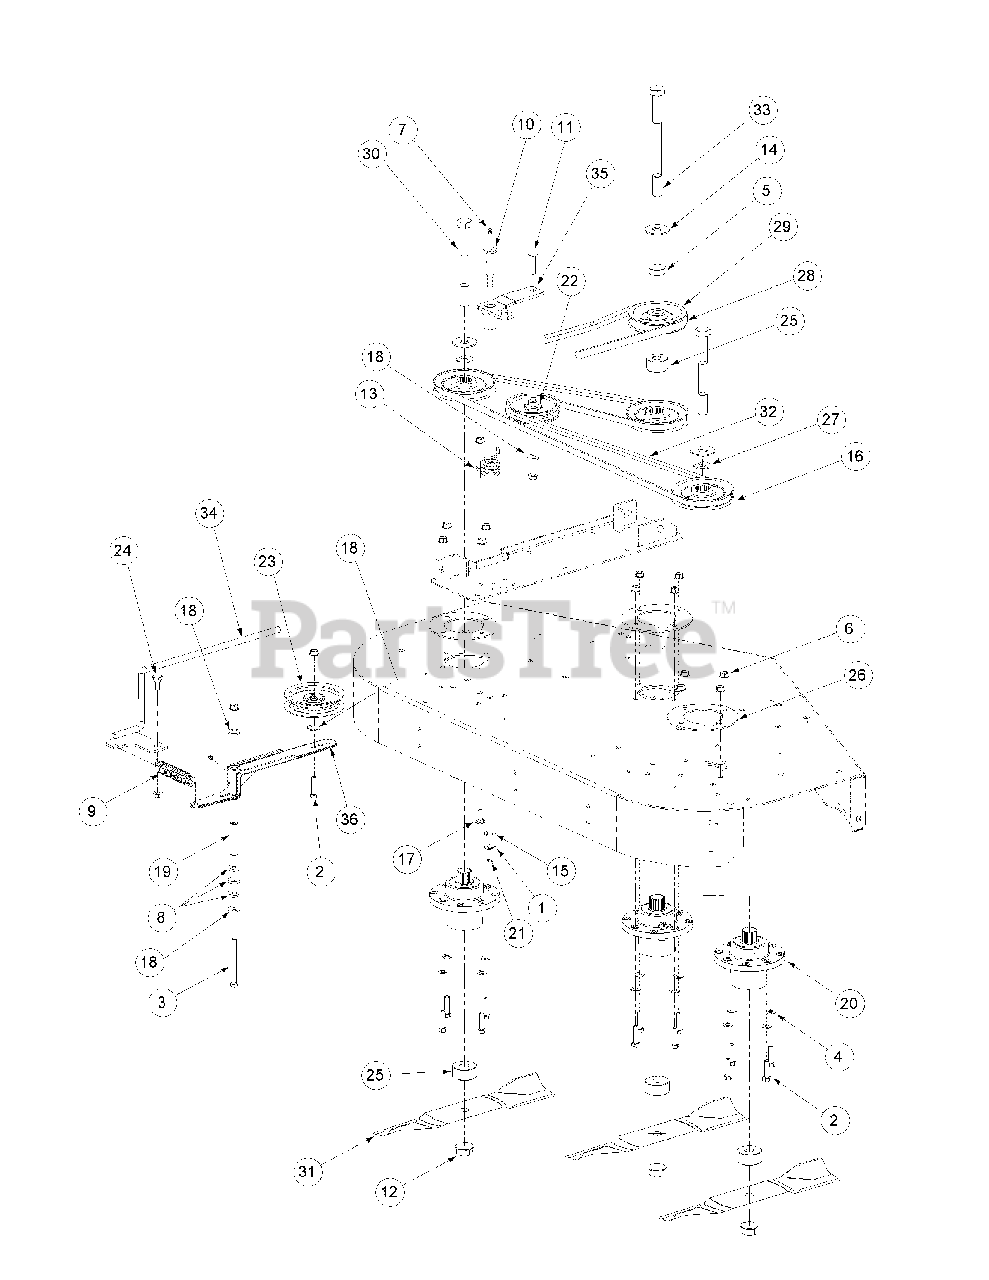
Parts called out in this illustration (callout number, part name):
1	Lock Washer, 7/16
2	Hex Cap Screw, 3/8-16 x 1-1/4
3	Hex Cap Screw, 3/8-16, 4.00
4	Flat Washer, 3/8
6	Hex Nut, Flange Lock, 3/8-16
7	Grease Fitting, 1/4-28 x 3/16
8	Idler Washer
9	Spring Extension, 1.0 OD x 5.125
10	Shoulder Screw, 7/16-14
11	Hex Carriage Screw, 3/8-16, 1.75
12	Hex Flange Nut, 3/4-16
13	Torsion Idler Spring
14	Flat Washer, .781 ID, 2.00 OD, .105
15	Flat Washer, .469 ID, .875 OD, .105
16	V-Pulley, 5.00 OD
17	Carriage Bolt, 3/8-16 x 1
18	Flat Washer, .406 ID, 1.0 OD, .105
19	Spacer, .39 ID x .625 OD x 2.75
20	Aluminum Spindle Assembly
21	Hex Nut, 7/16-14
22	Flat Pulley
23	Idler Pulley, 4.06 OD w/Deep Flange
24	Shoulder Screw, .50 x .27 Lg., 3/8-16
25	Spacer, .760 ID x 2.000 OD x 1.1
26	Spindle, Aluminum Cast Support Plate
27	Spacer, .812 ID x .218 LG
28	V-Belt, B Section x 83.2
29	V-Pulley, 4.75 OD
30	Hex Cap Screw, 3/4-16, 7.00
31	Blade, 17.0, Hi-Lift, 0.756 ID
32	V-Belt, A Section x 105.3
33	Hex Cap Screw, 3/4-16, 9.00
34	Spring Tension Rod Assembly
35	Idler Arm Assembly, Deck Spindle includes:
36	Idler Arm Assembly, Flat Top Bearing
